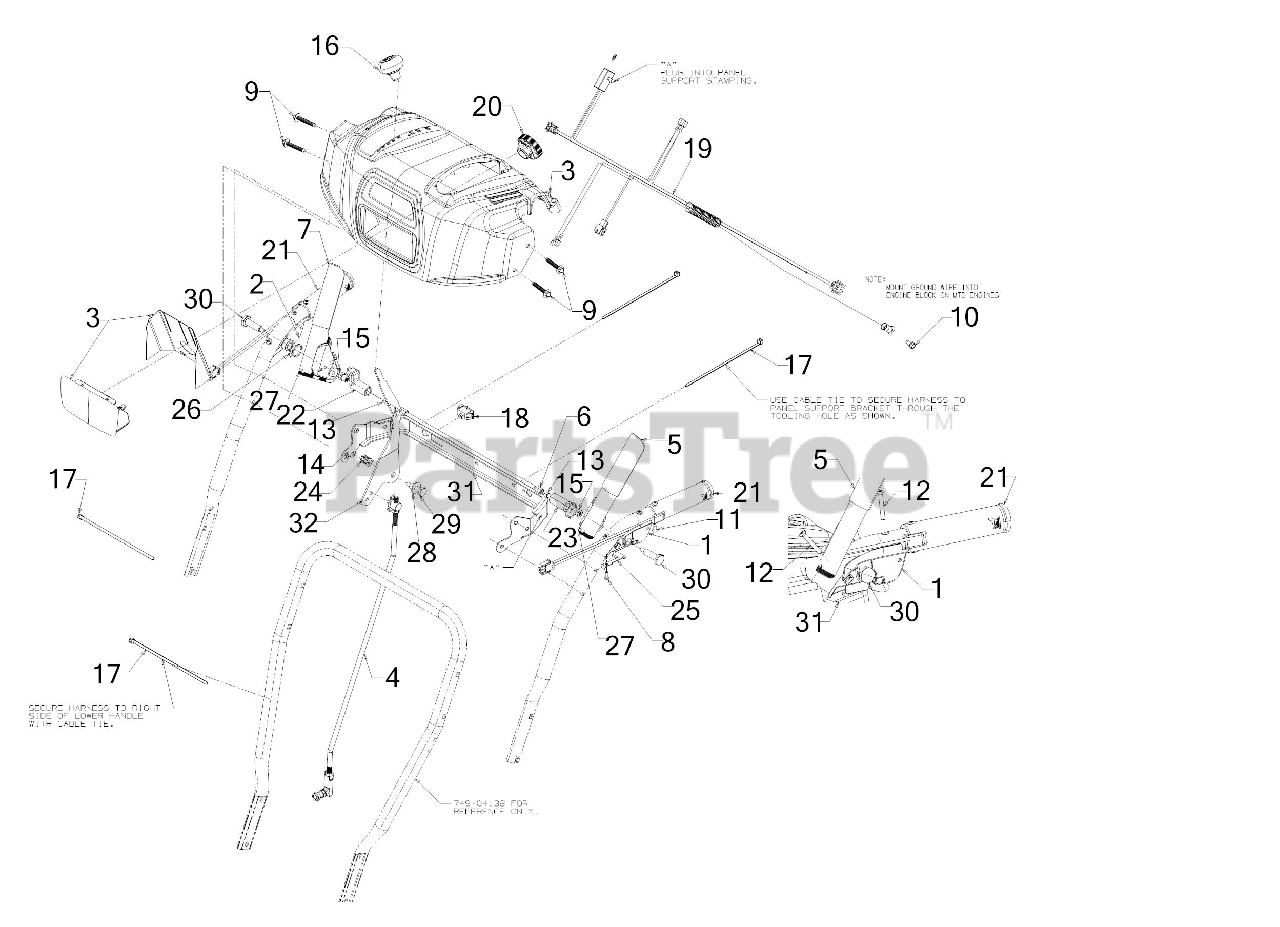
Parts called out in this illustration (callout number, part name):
1	CLUTCH LOCK HANDLE ASSEMBLY (LH)
2	CLUTCH LOCK HANDLE ASSEMBLY (RH)
3	HANDLE PANEL ASSEMBLY
4	SHIFT ROD ASSEMBLY
5	HANDLE ASSEMBLY (LH)
7	HANDLE ASSEMBLY (RH)
8	SCREW #8-16 x .50
9	SCREW 1/4-20 x 1.625
10	SCREW 1/4-20 X.500
11	SCREW #10-16 x .625
12	SCREW #10-24 x 1.375
13	SCREW 1/4-20 x .50
14	FLANGE LOCK NUT
15	HEX NUT W/PATCH
16	SHIFT KNOB
17	7" CABLE TIE
18	HEATED GRIP SWITCH
19	HEATED GRIP HARNESS
20	HEADLIGHT ASSEMBLY
23	CLUTCH LOCK CAM
24	COMPRESSION SPRING
25	CLUTCH SPRING
26	TORSION SPRING
27	RUBBER BUMPER
28	FLAT WASHER
29	SHOULDER SCREW
30	SHOULDER SCREW .437 x 1.345 1/4-20
31	HANDLE SUPPORT BRACKET
